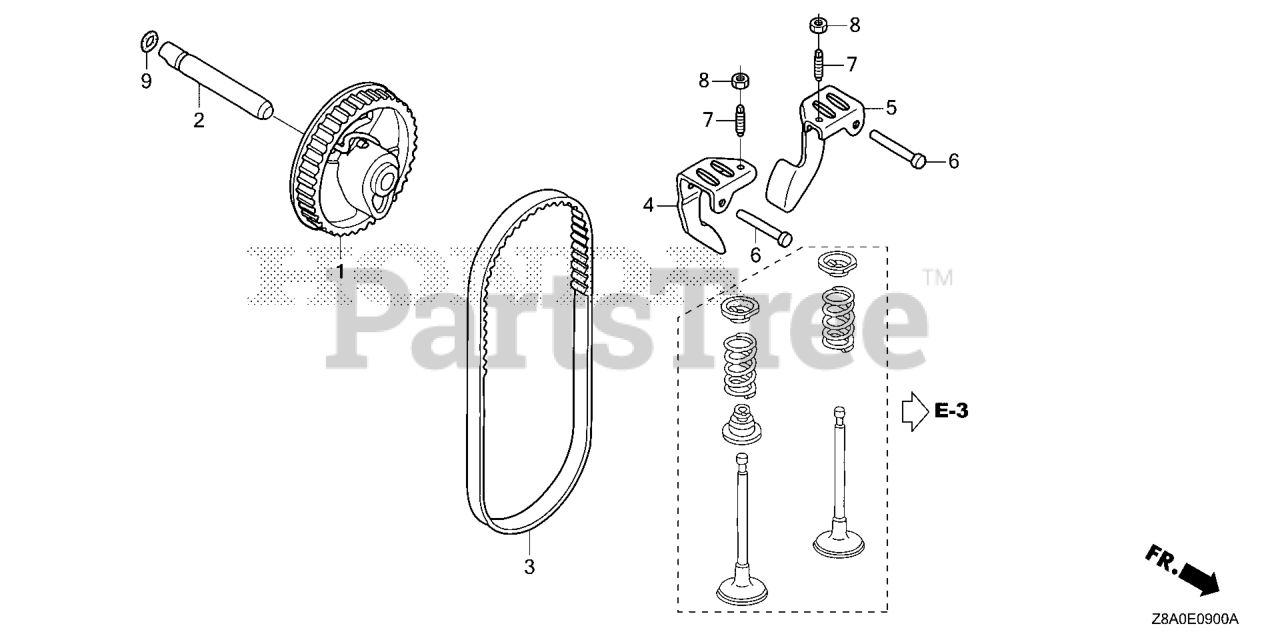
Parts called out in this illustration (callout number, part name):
1	PULLEY, CAMSHAFT
2	SHAFT, CAM PULLEY
3	BELT, TIMING (84HU6 G-200)
4	ARM, IN. VALVE ROCKER
5	ARM, EX. VALVE ROCKER
6	SHAFT, ROCKER ARM
7	SCREW, TAPPET ADJ.
8	NUT, TAPPET ADJ.
9	O-RING (6.8X1.9) (ARAI)
